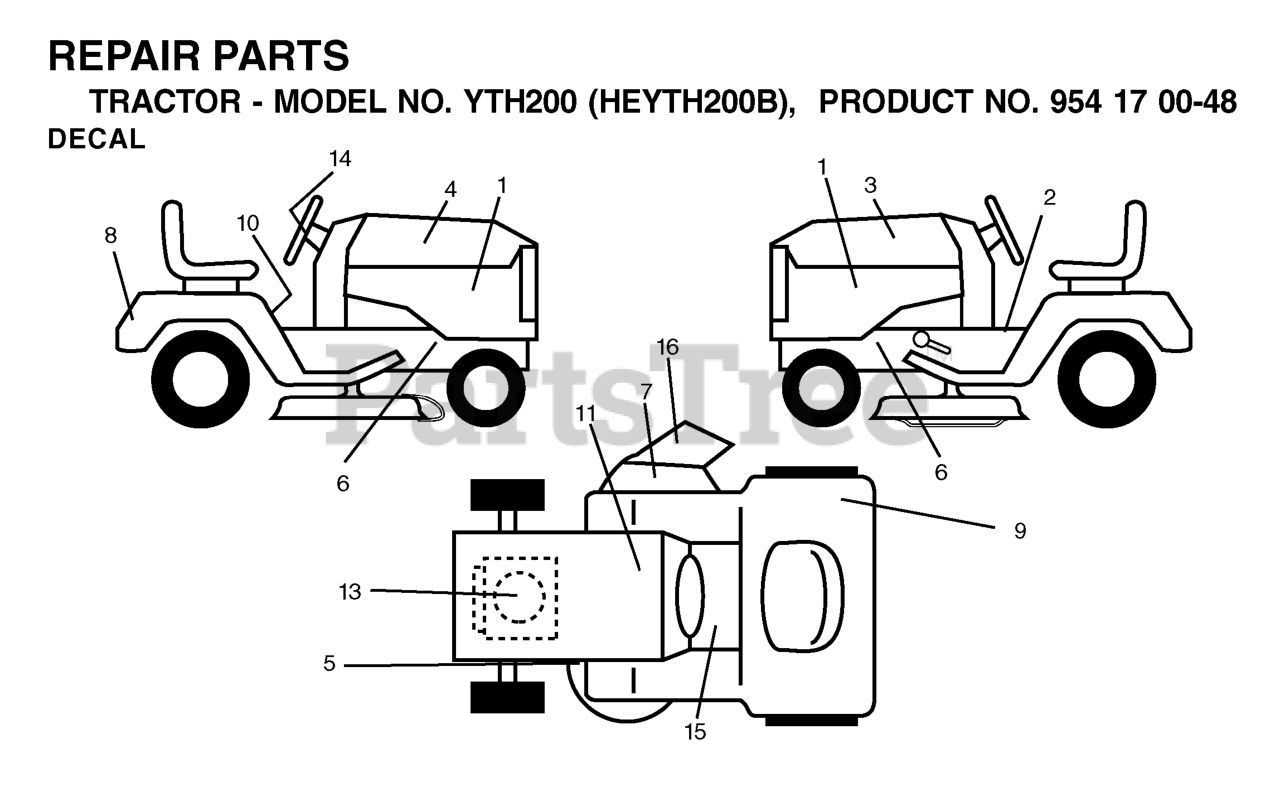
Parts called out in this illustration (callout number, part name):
1	DECAL PNL SIDE
2	DECAL PARK BRAKE
5	DECAL V BELT SCHEMATIC
7	DECAL.INTERNATIONL.CUTFINGER
8	DECAL FENDER HUSQ
9	Decal, Fender 100 DB/CE
10	DECAL READ OWNER'S MAN SYMS
11	DECAL BTRY SYMBOLS
14	DECAL.WHEEL.STEERING.HUSQ.PERM
15	DECAL
16	DECAL DECK "B" 42"
